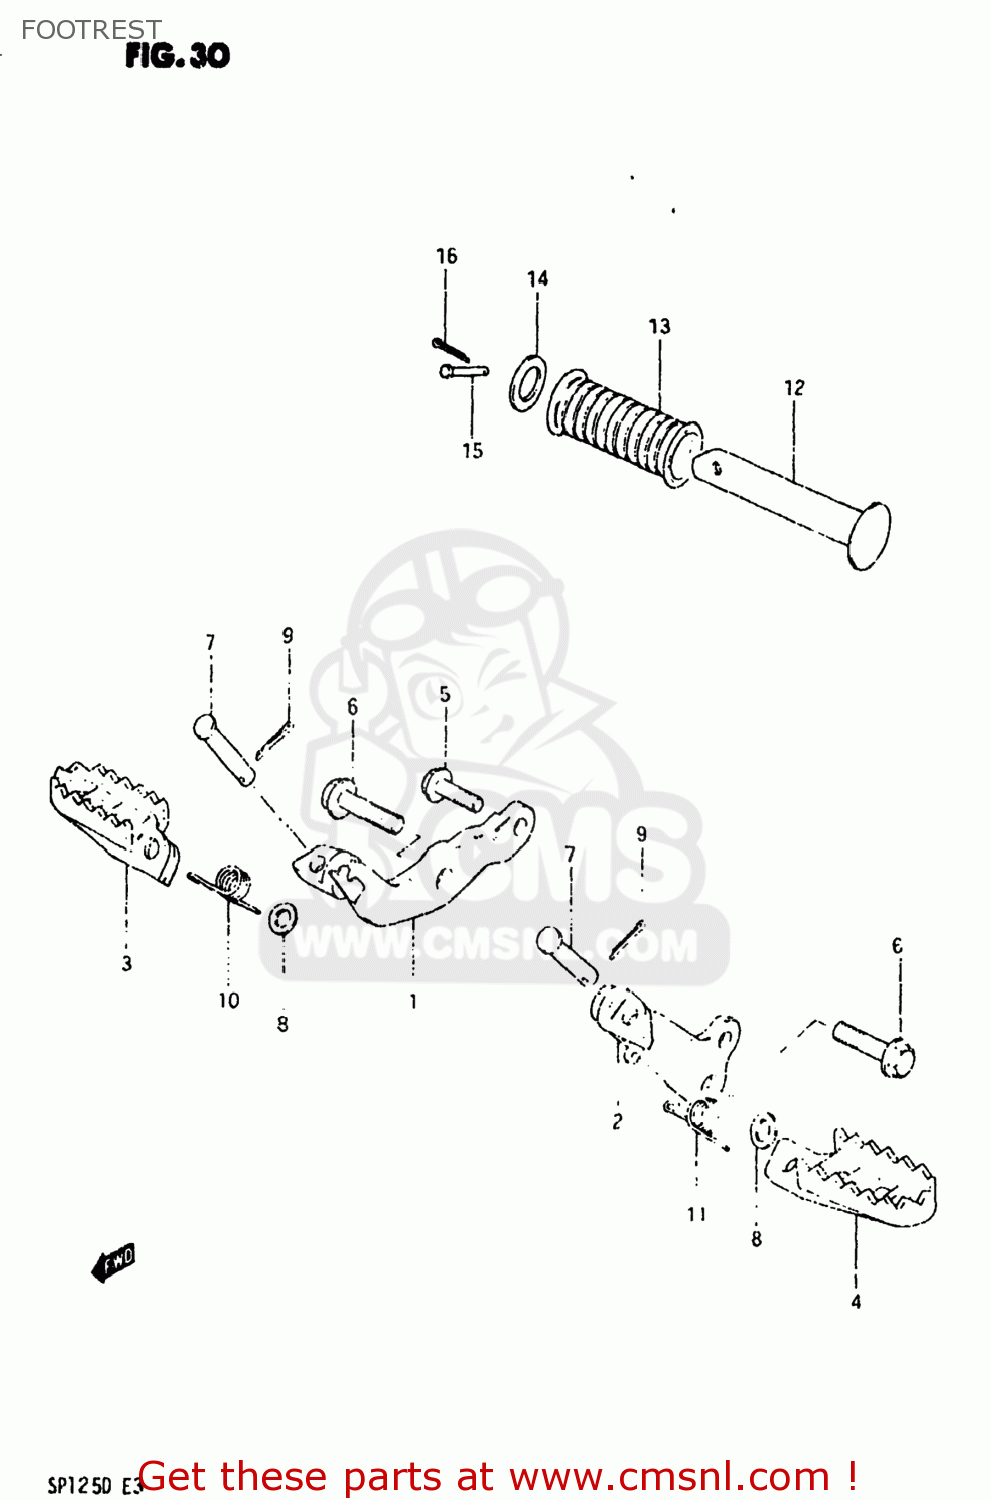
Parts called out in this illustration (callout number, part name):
1	BAR,FRONT FOOTREST
2	BAR,FRONT FOOTREST,LEFT
3	FOOTREST,RIGHT
4	FOOTREST
5	BOLT
6	BOLT
7	PIN
8	WASHER
9	PIN 20X20
10	SPRING
11	SPRING,FOOTREST,LEFT
12	BAR,FOOTREST RUBBER
13	RUBBER,PILLION FOOTREST
14	WASHER (19.5X32X2)
15	PIN
16	PIN 20X20
